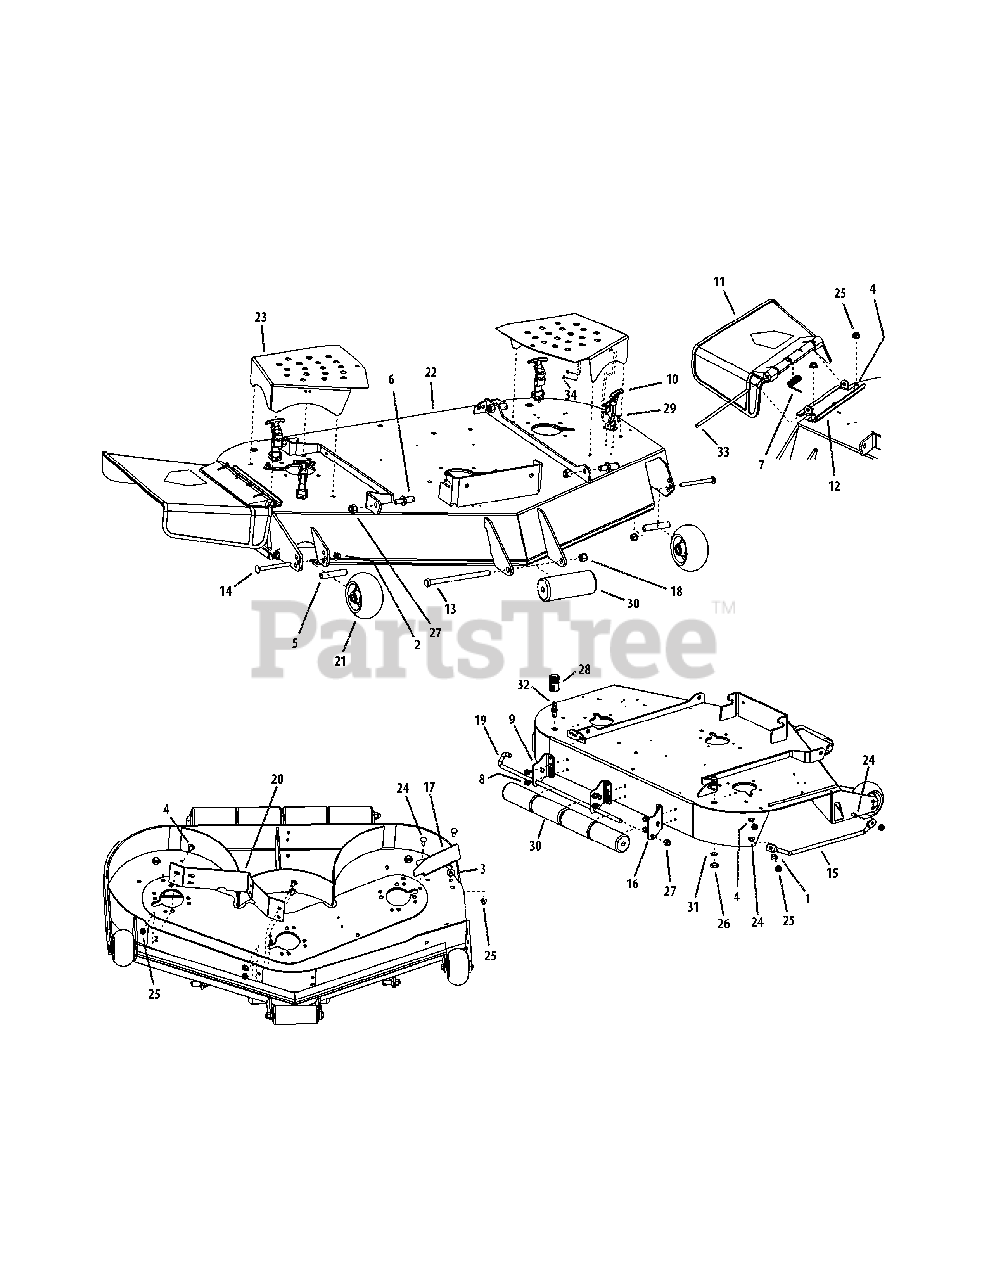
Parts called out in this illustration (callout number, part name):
1	Flat Washer, 3/8
2	Flange Lock Hex Nut, 3/8-16
3	Idler Washer
4	Carriage Bolt, 3/8-16 x .75 Lg.
5	Wheel Spacer
6	Pin, 5/8 Dia. x 1.2 Lg.
7	Spring Torsion, 0.639 ID x 2.16 LG
8	Hex Index Washer Screw, 3/8-16, .05
10	T-Handle Latch Draw
11	Deflector Chute
12	Deflector Chute Bracket
13	Hex Cap Screw, 1/2-20 x 7.50
14	Carriage Bolt, 3/8-16 x 4.00
15	Finger Guard
16	Deck Roller Mount Bracket, Right
18	Lock Nut, Nylon Insert, 1/2-20
19	J-Hook w/ Threaded Roller
20	48" Adjustment Baffle
21	Complete Wheel, 5.00 Dia.
22	48" Deck Assembly
23	Deck Belt Cover
24	Carriage Bolt, 3/8-16 x 1
25	Lock Nut, Nylon Insert, 3/8-16
26	Hex Nut, M16-1.5
27	Lock Nut, Nylon Insert, 1/2-13
28	Water Nozzle Adaptor
29	Phillips Head Screw, #10-32 x 1/2
30	Front Roller
31	Lock Washer, 17 x 23.8 x 1.95
32	Deck Water Nozzle
33	Chute Deflector Rod
34	Lock Nut, Nylon Insert, #10-32
